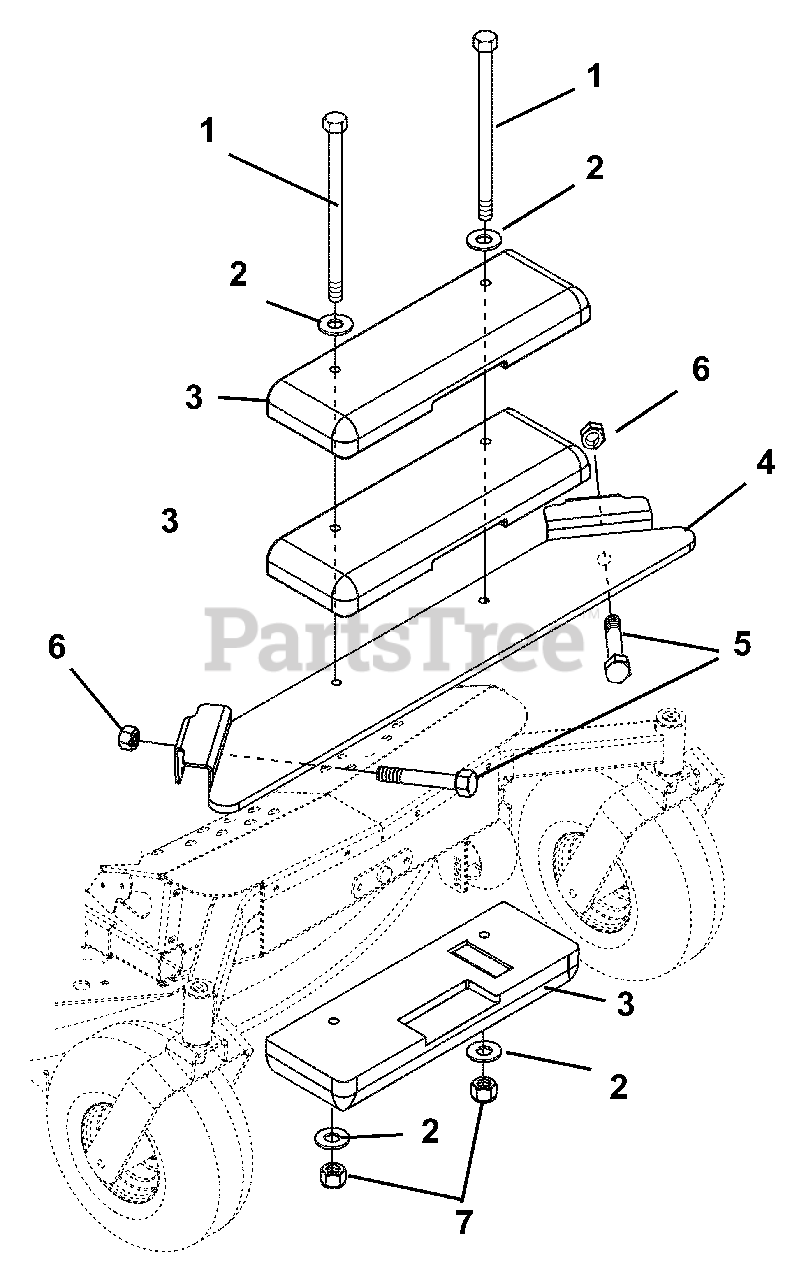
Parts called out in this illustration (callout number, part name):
1	@BLT-HEX .50-13X7.50 GR5 YWZC
2	WSHR-FL-STL .505X1.00X.062YWZC
3	WEIGHT-REAR FRAME
4	WELDMENT-260Z COUNTER WEIGHT
5	@BLT-HEX .38-16X3.00 GR5 YWZC
6	@NUT-LK-NYL .38-16 YWZC
7	@NUT-LK-CTR .50-13 YWZC
